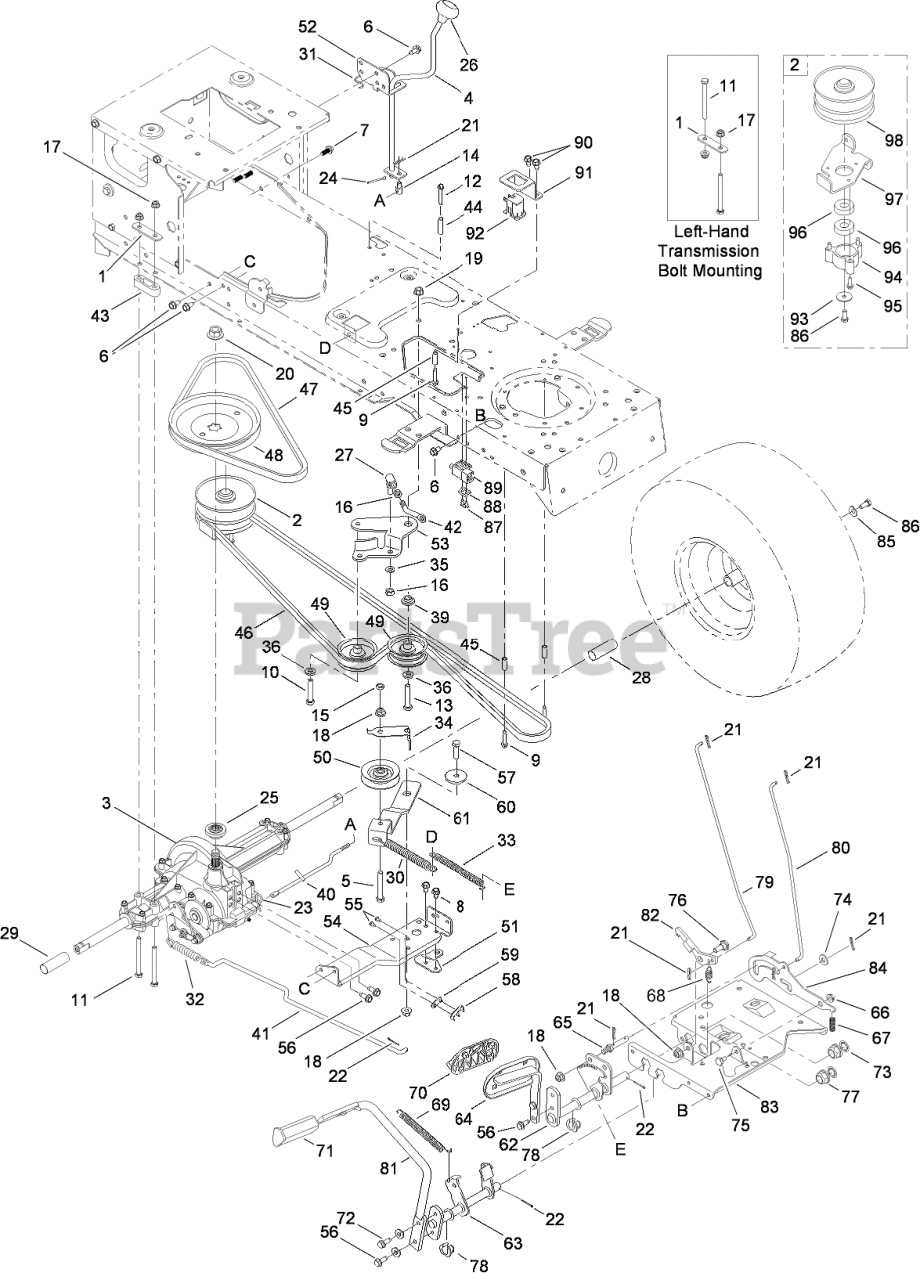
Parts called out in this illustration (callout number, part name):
1	BRACKET-MOUNTING, TRANSMISSION
2	PULLEY ASM
3	SINGLE SPEED TRANSAXLE ASM
4	SHIFT LEVER ASM
5	SCREW-HH
6	SCREW-TAP
7	SCREW-HH
8	SCREW-TAP
9	SCREW-HH
10	SCREW-TAP
11	SCREW-HH
12	SCREW-TAP
13	SCREW-HH
14	FERRULE-ADJUSTABLE
15	NUT-JAM, LOCK
16	NUT-HEX
17	NUT-LOCK, FLANGE
18	NUT-LOCK, FLANGE
19	NUT-LOCK, FLANGE
20	NUT-FLANGE
21	PIN-COTTER
22	PIN-COTTER
23	PIN-HAIR
24	PIN-COTTER
25	HUB-PULLEY
26	KNOB-SHIFT
27	BALL JOINT ASM
28	SLEEVE
29	SLEEVE
30	SPRING-EXTENSION
31	CLIP-SPRING, SHIFTER
32	SPRING-EXTENSION
33	SPRING-EXTENSION
34	GUIDE-BELT, TRACTION
35	WASHER-LOCK
36	WASHER-FLAT
39	SPACER-SHOULDER
40	ROD-SHIFT
41	ROD-BRAKE
42	ROD-ADJUSTMENT, IDLER
43	SPACER-TRANSAXLE
44	SPACER
45	SPACER
46	BELT-DRIVE, VARIABLE SPEED
47	BELT-DRIVE, TRANSMISSION
48	PULLEY-V (W/HUB)
49	PULLEY-IDLER, FLAT
50	PULLEY-IDLER, V-TYPE
51	BRACKET-SHIFT
52	BRACKET-SHIFT
53	BRACKET-IDLER, CENTER DOUBLE
54	BRACKET ASM
55	SCREW-HWHTF
56	SCREW-HWH
57	SCREW-HH
58	SWITCH-SPRING, SHORT
59	PLATE-INSULATOR
60	SPACER-SHOULDER
61	BRACKET-IDLER
62	SPEED CONTROL ASM
63	SPEED CONTROL ASM
64	PEDAL ASM
66	NUT-LOCK, FLANGE
67	SPRING
68	SPRING-EXTENSION
69	SPRING-EXTENSION
70	PAD-PEDAL
71	PAD-BRAKE
72	WASHER-LOCK
73	WASHER-FLAT
74	Washer-Flat
75	BOLT-SHOULDER
76	BOLT-SHOULDER
77	BEARING-FLANGE
78	BEARING-FLANGE, HEX (SPLIT)
79	ROD-BRAKE, LOCK CONTROL
80	ROD-CONTROL, CRUISE
81	PEDAL-BRAKE
82	LATCH-CRUISE
83	BRACKET-SUPPORT, STEERING
84	BRACKET-LOCKOUT
85	WASHER-BELL
86	SCREW-HH
87	SCREW-TAP
88	PLATE-SWITCH
89	SWITCH-INTERLOCK
90	SCREW-HWHTF
91	BRACKET-SWITCH, PARKING BRAKE
92	SWITCH-MOUNT, SNAP
93	WASHER-FLAT
94	CUP-BEARING
95	SCREW-HWH
96	BEARING-BALL
97	BRACKET-PULLEY
98	PULLEY ASM
